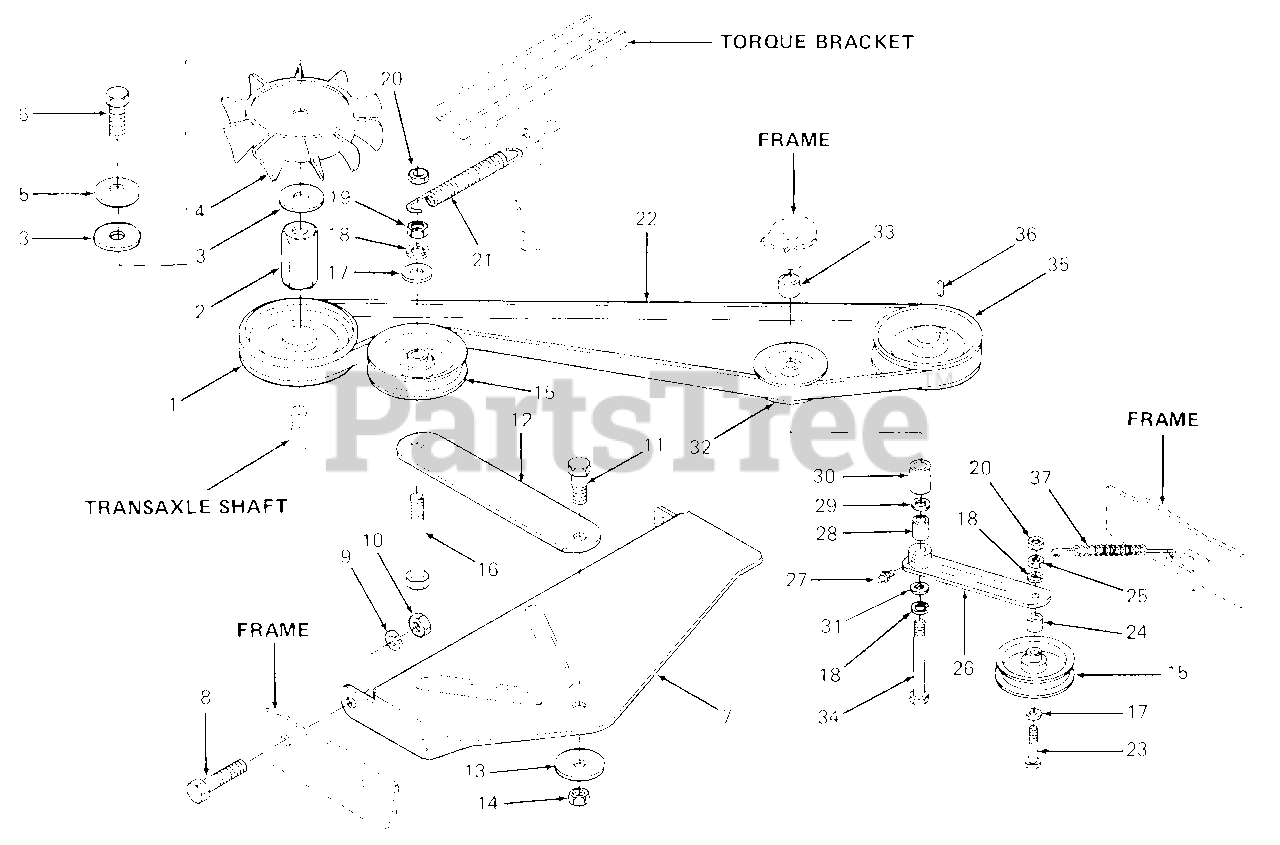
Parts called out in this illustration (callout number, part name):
1	V-Pulley, 4.0 Dia
2	Adapter, Fan, 1.0 Lg
3	Washer, Flat, .531 X 1.5 X .120 Thk
4	Fan, 10 Blade Hydro
5	Washer, Bell, .505 X 1.00 X .075
6	Bolt, Hex, 1/2-20 X .75 Lg GR5
7	Bracket, Clutch Mounting
8	Screw, Hex Cap, 5/16-18 X .62 Lg
9	Washer, Lock, 5/16
10	Nut, Hex, 5/16-18 GR5
11	Screw, Shoulder
14	Nut, Hex Center Lock, 5/16-18 GR5
15	Idler, Flat, 2.75 Dia
16	Screw, Hex Cap, 3/8-16 X 2.25 Lg GR5
17	Washer, Flat, .406 X .75 X .063 Thk
18	Washer, Lock, 3/8
19	Nut, Hex, 3/8-16 GR5
20	Nut, Hex Center Lock Jam, 3/8-16
21	Spring, Extension
22	V-Belt, A Sec X 80 in. Lg
23	Screw, Hex Cap, 3/8-16 X 2.75 Lg GR5
24	Spacer, .375 X .625 X .445 Lg
25	Nut, Hex Jam, 3/8-16 GR5
27	Fitting, Lube, 3/16 Drive
28	Spacer, .3775 X .600 X .830 Lg
29	Washer, Flat, .385 X .87 X .06 Thk Hdn
30	Spacer, .38 X .75 X 1.26 Lg
31	Washer, Flat, .406 X 1.25 X X .157 Thk
32	V-Idler, 2.62 OD
33	Bushing, .39 X 1.0 X .812 Lg
34	Bolt, Hex, 3/8-16 X 4.75 Lg GR5
35	Pulley, Engine, 3.5 Dia
36	Key, Square, 1/4 X .75 Lg
37	Spring, Extension
